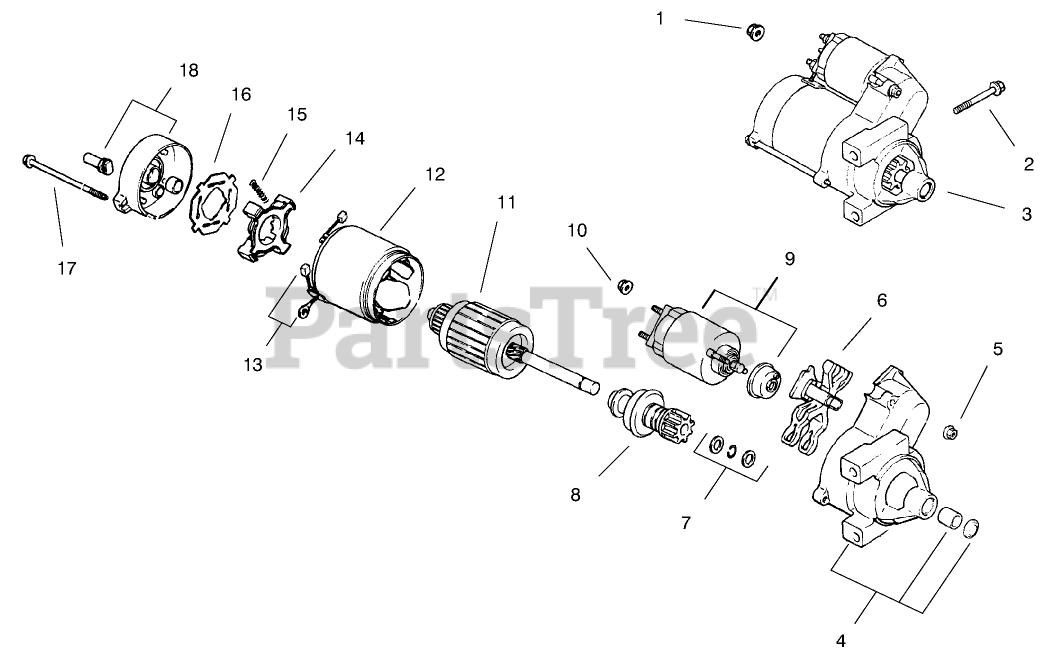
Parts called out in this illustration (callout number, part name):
1	Nut
2	Scew
3	Starter, solenoid shift (Includes 4-18)
4	Cap-Drive End
5	Nut
6	Lever Starter Drive
7	Washer
8	Drive Pinion
9	Solenoid
10	Nut
11	Armature-Starter
12	Frame
13	Kit, brush & spring (Includes 15)
14	Holder-Brush
15	Spring Brush
16	Insulator
17	Bolt
18	Commutator-End Cap
